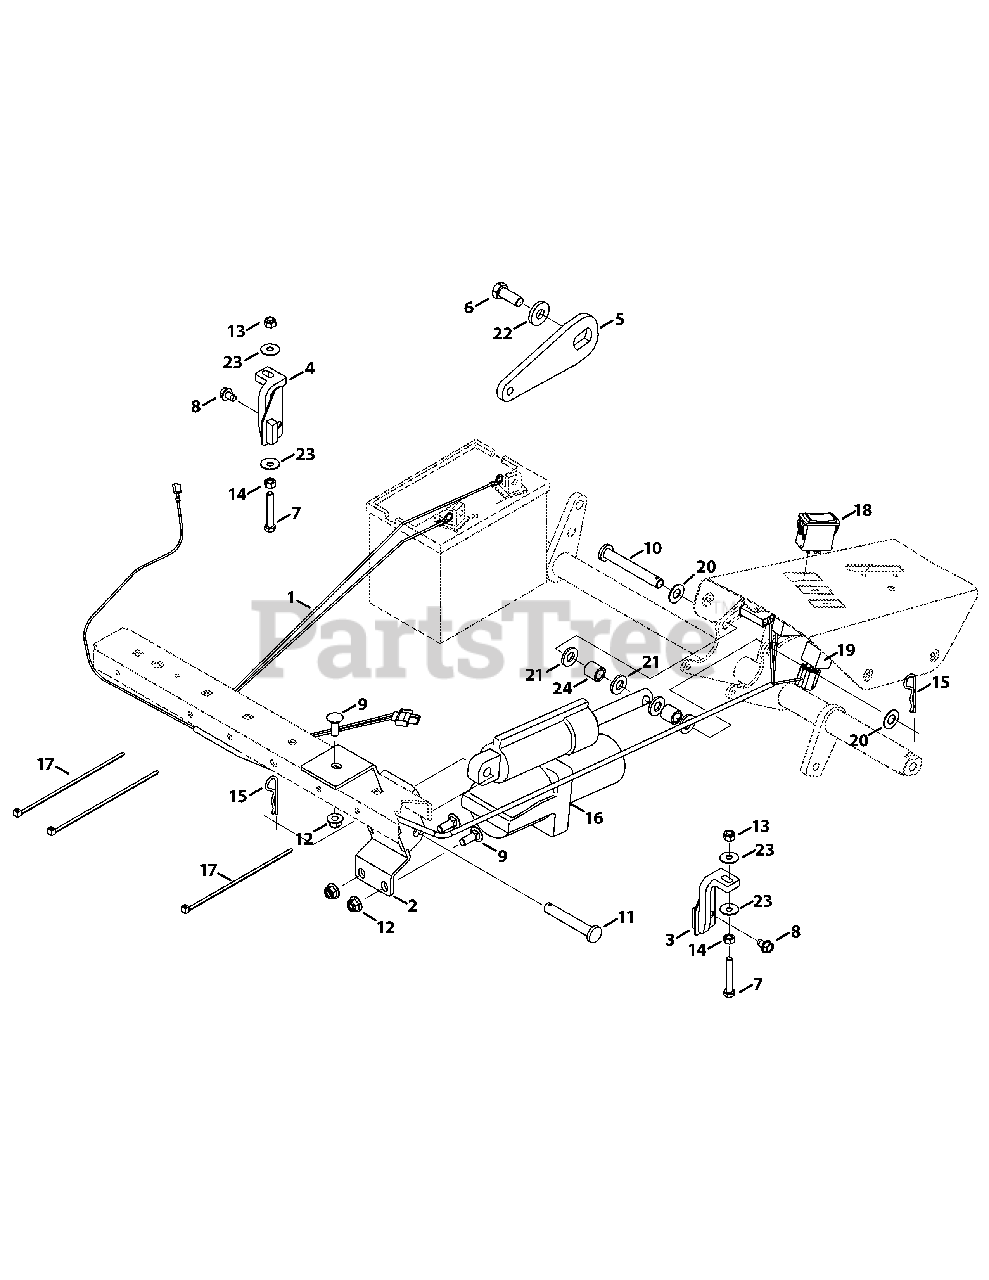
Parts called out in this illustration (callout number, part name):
1	Deck Lift Harness
2	Deck Lift Cylinder Mount
3	RH Lift Lock Mount
4	LH Lift Lock Mount
6	Hex Screw, 1/2- x 1.25
7	Hex Screw, 5/16-24 x 2.00
8	Hex Wshr. Screw, 5/16-18 x .500
9	Carriage Bolt, 3/8-16 x 1.00
10	Clevis Pin, .500 x 3.75
11	Clevis Pin, .500 x 3.2
12	Flange Lock Nut, 3/8-16
13	Hex Lock Nut, 5/16-24
14	Hex Nut, 5/16-24
15	Cotter Pin, .125 x 2.5
16	Lift Cylinder
17	Cable Tie, 3/16 x .05 x 7.4
18	Deck Lift Switch
19	SPDT Relay
20	Flat Washer, .510 x 1.000 x .060
21	Flt. Washer, .510 x 1.000 x .125
22	Flt. Washer, .531 x 1.25 x .181
23	Washer, .325 x .930 x .045
24	Spacer, .501 x .750 x .775
